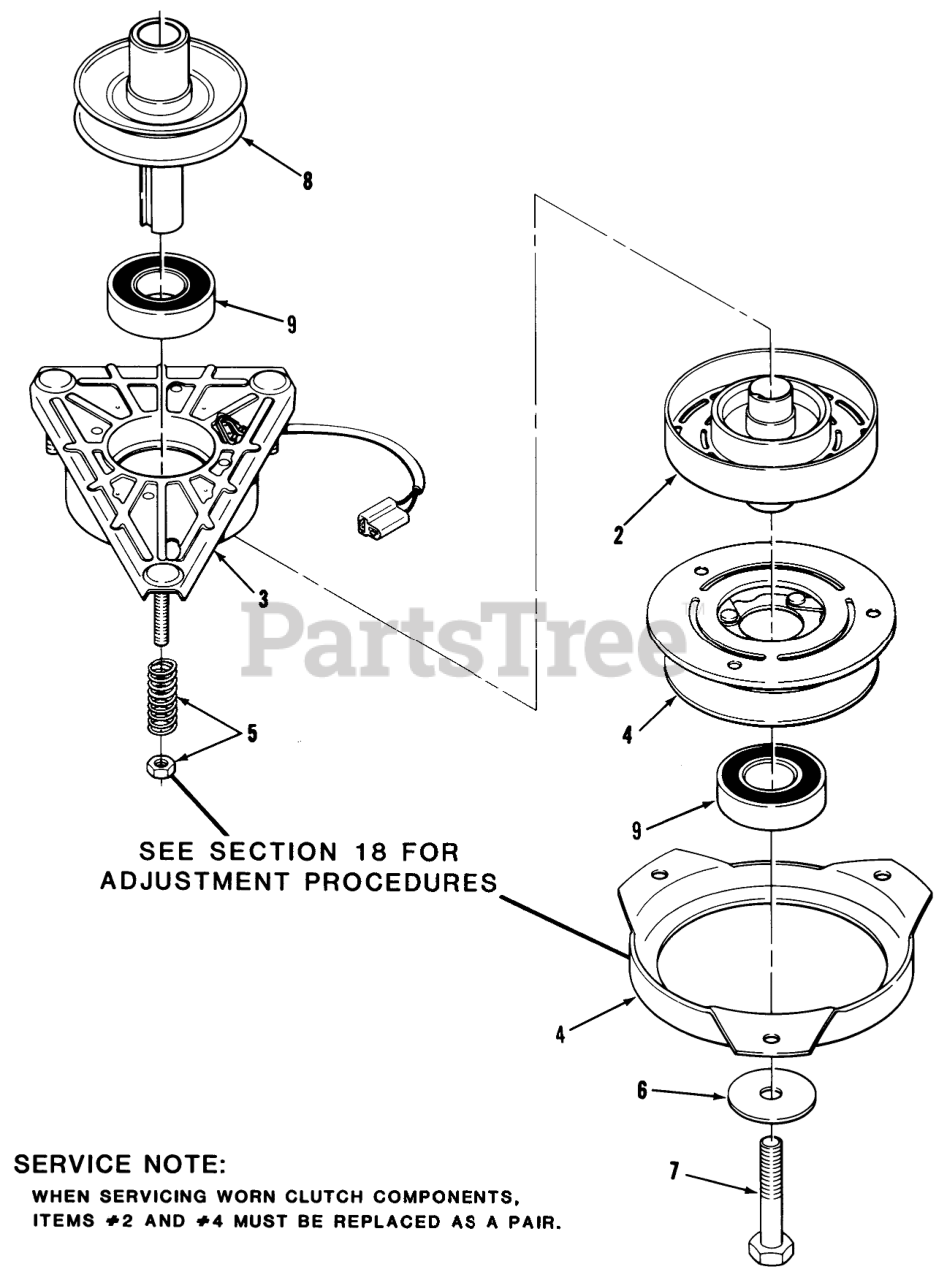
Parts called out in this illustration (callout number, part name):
1	Electric Clutch Assembly (Incl. Ref. #2-5)
2	ASS'Y-ROTOR
3	Field Assembly (Incl. Ref. #9)
4	Armature & Pulley Assy. (Incl. Ref. #9)
5	ACCESS SPRING & NUT
6	WASHER
7	Bolt
8	PULLEY-ENGINE
9	BEARING-ELEC CLUTCH
